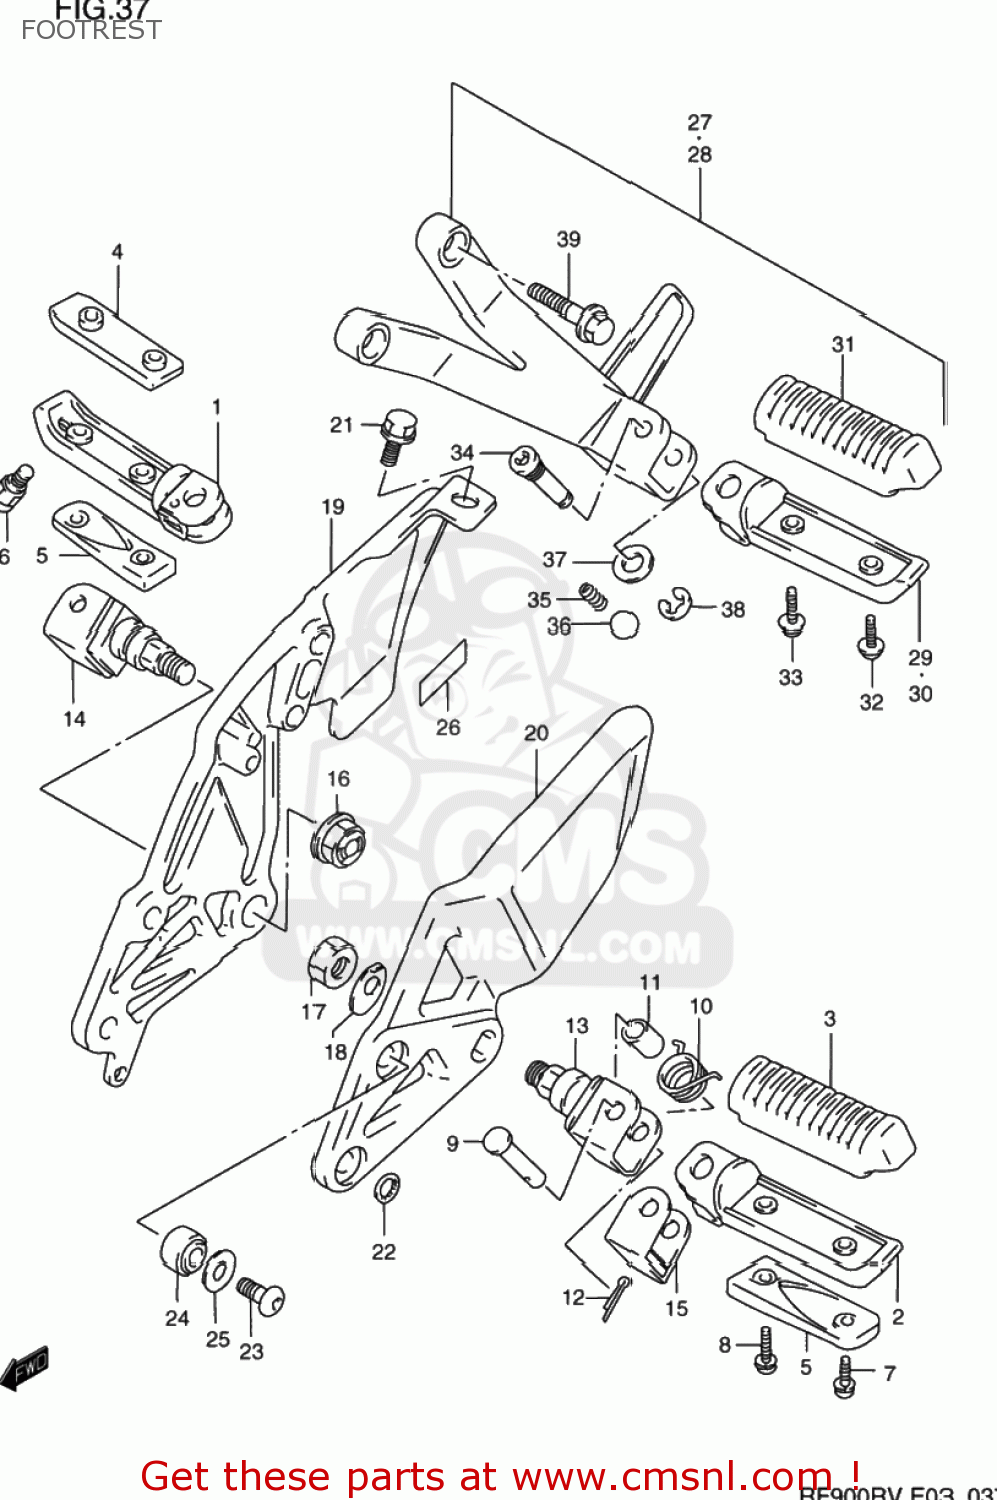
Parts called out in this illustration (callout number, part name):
1	BAR,FR FOOTREST,R
2	BAR,FOOTREST,L
3	RUBBER,FOOTREST
4	BAR,FR FOOTREST NO.2
5	BALANCER,FR FOOTREST LWR
6	SENSOR,FOOTREST
7	SCREW
8	SCREW
9	PIN
10	SPRING
11	SPACER(8.1X12X22)
12	PIN 20X15
13	HOLDER,FRONT FOOTREST
14	HOLDER,FR FOOTREST
15	CUSHION,FR FOOTREST
16	NUT 12MM
17	NUT
18	WASHER,FR FOOTREST
19	BRACKET,FOOTREST,R
20	BRACKET,FOOTREST,L
21	BOLT
22	WASHER
23	BOLT(8X25)
24	BUSH
25	WASHER (8.2X24X1.6)
26	PROTECTOR(12X40)
27	FOOTREST ASSY,PILLION,R
28	FOOTREST ASSY,PILLION,L
29	BAR,PILLION FOOTREST,R
30	BAR,PILLION FOOTREST,L
31	RUBBER,FOOTREST
32	SCREW
33	SCREW
34	BOLT,PILLION FOOTREST
35	SPRING
36	BALL
37	WASHER
38	E.RING
39	BOLT(8X20)
